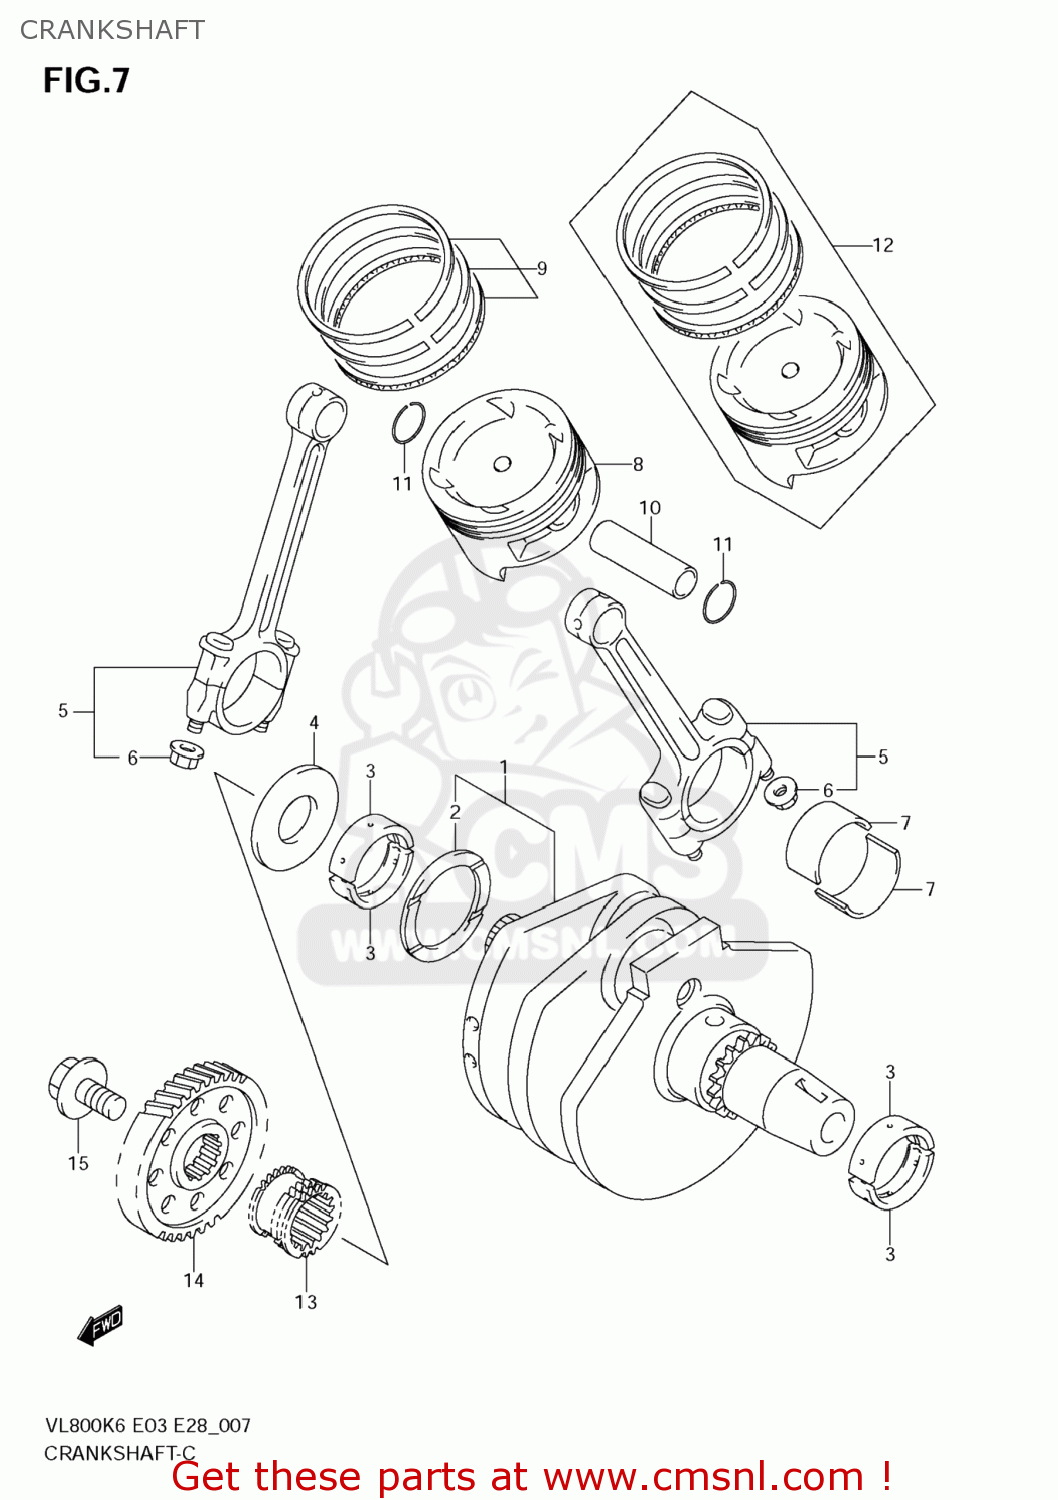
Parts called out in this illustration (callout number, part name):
1	CRANKSHAFT SET
2	WASHER(48.1X64X1.94)
3	BEARING,CRANKSHAFT
4	WASHER,CRANK THRUST
5	CONNECTING ROD ASSY
6	NUT
7	BEARING,CRANK PIN
8	PISTON
9	RING SET,PISTON
10	PIN,PISTON
11	CIRCLIP,PISTON PIN
12	PISTON SET,OS0
13	SPROCKET,CAM CHAIN DRIVE,R
14	GEAR,PRIMARY DRIVE
15	BOLT(12X28)
